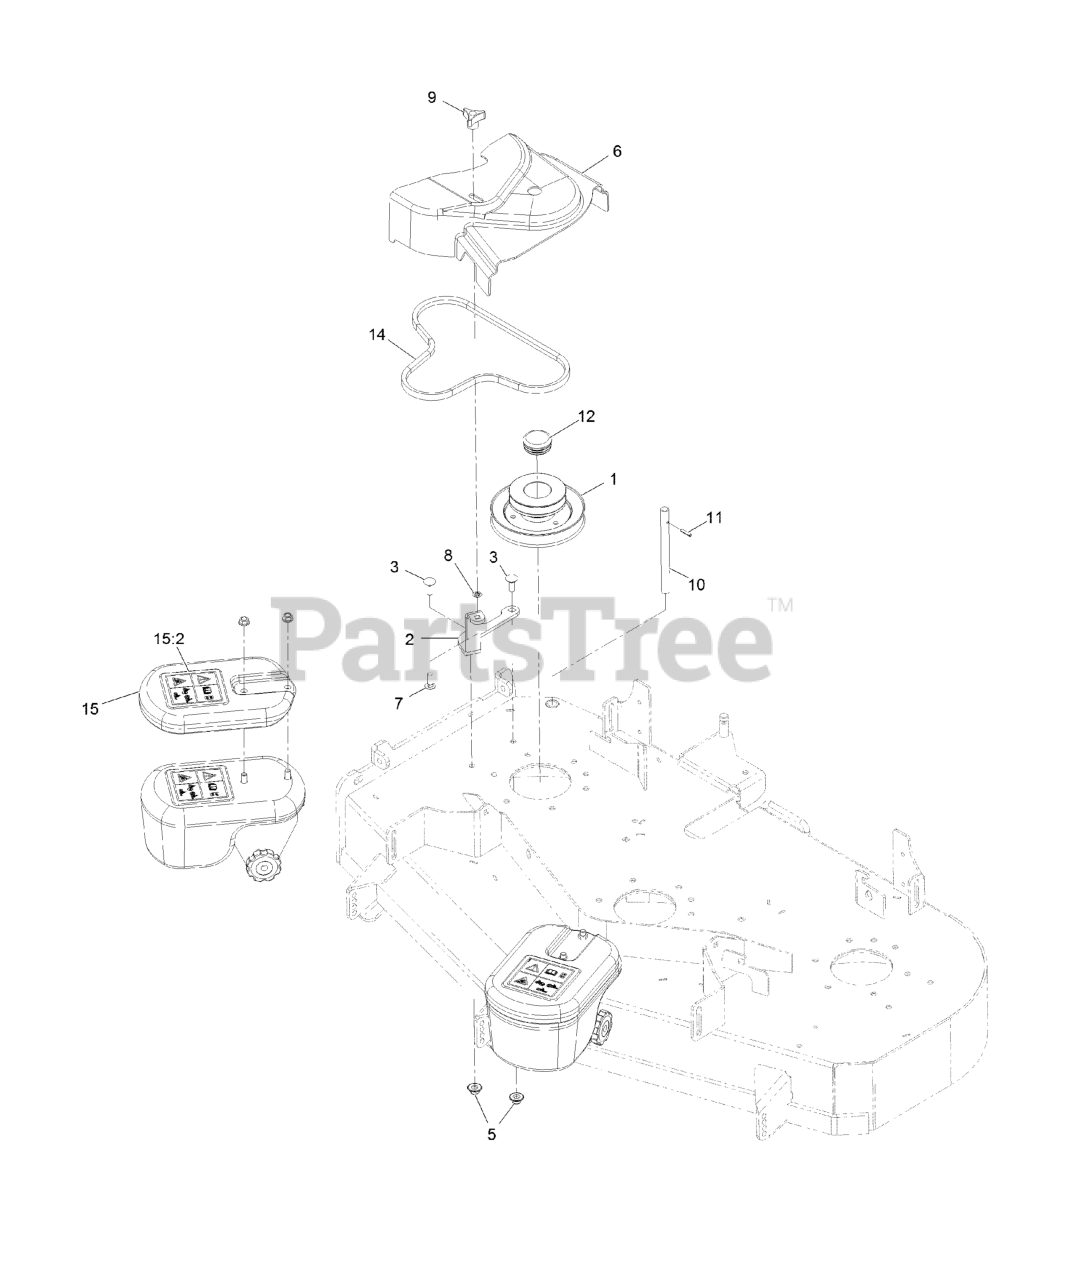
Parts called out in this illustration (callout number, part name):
1	JACKSHAFT-UV DRIVE, 484 SPLINED
2	BRACKET, SMALL UV BELT COVER
3	BOLT-CARR
5	Nut-Nyloc 3/8-16 Flg
6	COVER-BELT, UV 48
7	BOLT-CARR
8	RING-RETAINING, BOLT
9	KNOB-3 PRONG
10	SHAFT-CATCHER, GRASS
11	PIN-ROLL
12	PLUG-ROUND PLASTIC
14	BELT-BLOWER
15:2	DECAL-WARNING, TRACTION
